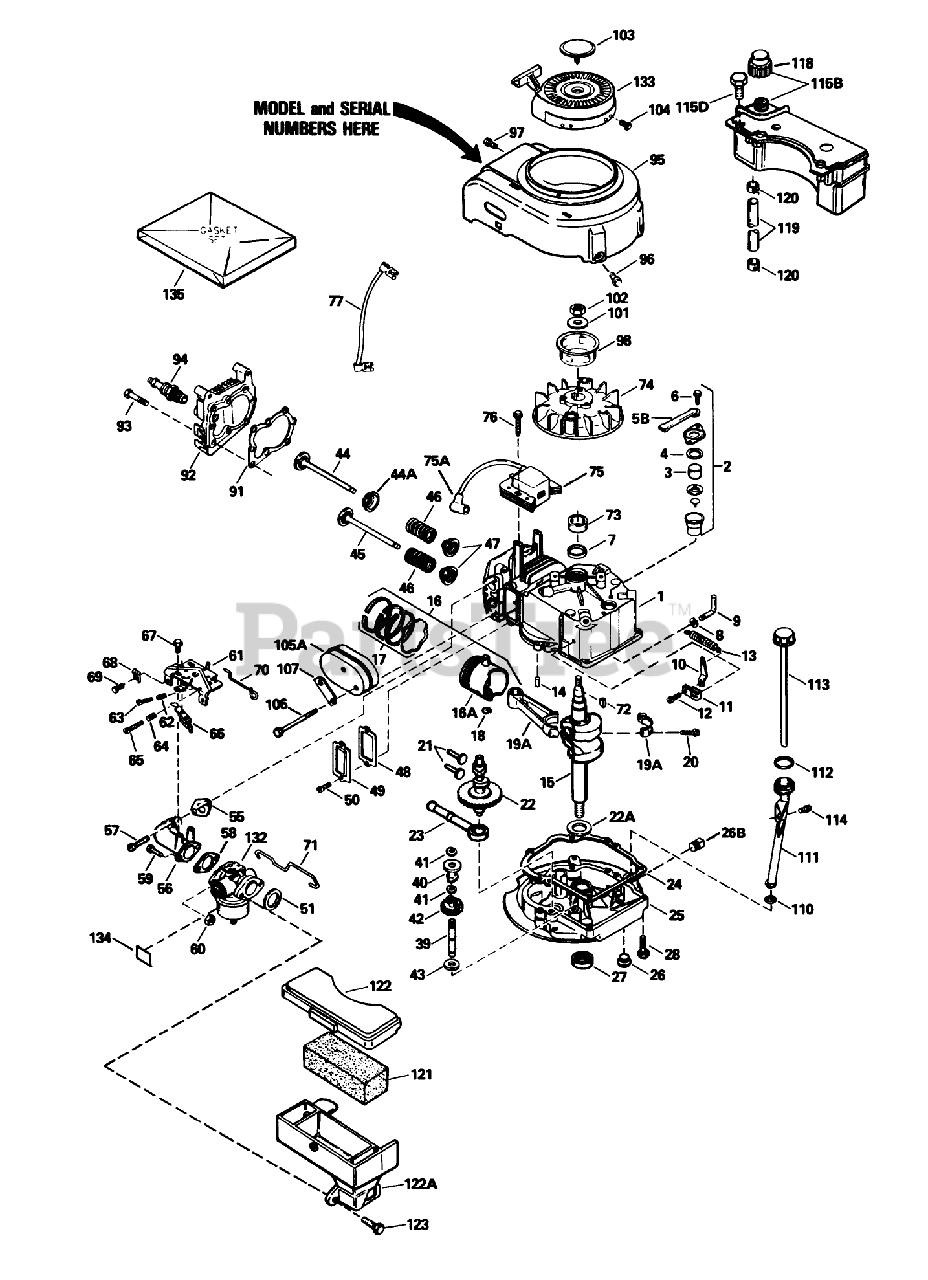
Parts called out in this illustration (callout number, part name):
1	Cylinder Assembly (Incl. Ref. #7 14)
2	Breather Assy. (Incl. Ref. #46 thru 51)
3	Element-Breather
4	Gasket-Breather
5B	Tube, Breaker
6	Screw (10-24 x 9/16)
7	Seal-Oil
8	Washer-Flat
9	Rod, Governor (Incl. No. 36)
10	Governor Lever
11	Clamp-Lever, Governor
12	Screw
13	Spring Governor
14	Pin-Dowel
15	Crankshaft Assembly
16	Piston-Pin Ring Assy. (Std.)(Incl. Ref. #16A, 17 18)
16	Piston-Pin Ring Assembly (.010 oversize)(Incl. Ref. #16A, 17 18)
16	Piston, Pin Ring Assy. (.020 Oversize)(Incl. Ref. #13A, 14, 15)
16A	Piston Pin Assy. (Std.)(Incl. Ref. #14)
16A	Piston Pin Assembly (.010 oversize)(Incl. Ref. #18)
16A	Piston Pin Assy. (.020 Oversize) (Incl. Ref. #14)
17	Ring Set-Piston (Std.)
17	Ring Set, Piston(.0100versize)
17	Ring Set (.020" OS)
18	Ring-Retaining, Piston Pin
19A	Rod Assembly, Connecting (Incl. Nos. 17 18)
20	Bolt-Rod, Connecting
21	Lifter-Valve
22	Camshaft(Mech.Comp. Release)
22A	Washer-Thrust
23	Oil Pump ASM
24	Gasket
25	Flange Assy., Mounting (Incl. Ref. #26 thru 30)
26	Plug Oil Drain
26B	Plug-Pipe
27	Seal-Oil
28	Screw (1/4-20 x 1-1/4)
39	Shaft-Governor
40	Spool-Governor
41	Ring-Retaining
42	Governor Gear ASM
43	Washer
44	Valve, Intake (Std.) (Incl. Ref. #40)
44	Valve, Intake (1/32" oversize)(Incl. No. 40)
44A	Seal Assy., Intake
45	Valve, Exhaust (Std.)(Incl. No. 40)
45	Valve, Intake (1/32" oversize)(Incl. No. 40)
46	Spring-Valve
47	Cap-Valve, Spring
48	Gasket-Cover, Valve
49	Cover-Valve
50	Screw
51	Gasket-Cleaner, Air
55	Gasket-Intake Pipe
56	Pipe-Intake (Incl. Ref. #59)
57	Screw (1/4-20 x 1)
58	Gasket
60	Nut and Lock Washer (1/4-28)
61	Control Assy.-Remote Speed (Incl. Ref. #69 thru 72 76)
62	61709/GIL1515A/95-5
63	Screw
64	Spring-Compression
65	Screw
66	Terminal
67	Screw (10-24 x 9/16)
68	Conduit
69	Screw (10-32 x 3/8)
70	2035A67 ADD.ASSEMBL
71	Link-Throttle
72	Key-Flywheel
73	Spacer
74	Flywheel
75	Solid State
75A	Cover-Spark Plug
76	Screw
77	Wire-Ground
91	Gasket-Cylinder Head
92	Head-Cylinder
93	Screw (5/16-18x1-1/2)
94	Spark Plug-Resistor (R J19 L M)
95	Housing-Blower
96	Screw (1/4-20 x 1/2)
97	Screw (10-24 x 9/16)
98	Hub-Starter
101	Washer-Belleville
102	Nut-Flywheel
103	Plug Starter
104	Screw, Hex Hd.
105A	Muffler
106	Screw
107	Plate-Lock
110	Gasket
111	Oil Fill Tube
112	O-Ring
113	Dipstick
114	Screw (10-32 x 1/2)
115B	Tank Assembly-Fuel (Incl. Ref. #102)
115D	Screw (10-32 x 35/64)
118	Cap-Fuel
119	Line-Fuel
120	Clamp-Line, Fuel
121	Filter-Air Cleaner
122	Cover Air Cleaner
122A	Body Air cleaner
123	Screw
132	Carburetor (Incl. Ref. #58)
133	Starter-Rewind
134	Decal-Primer
135	Gasket Set (Incl. Items Marked *)
